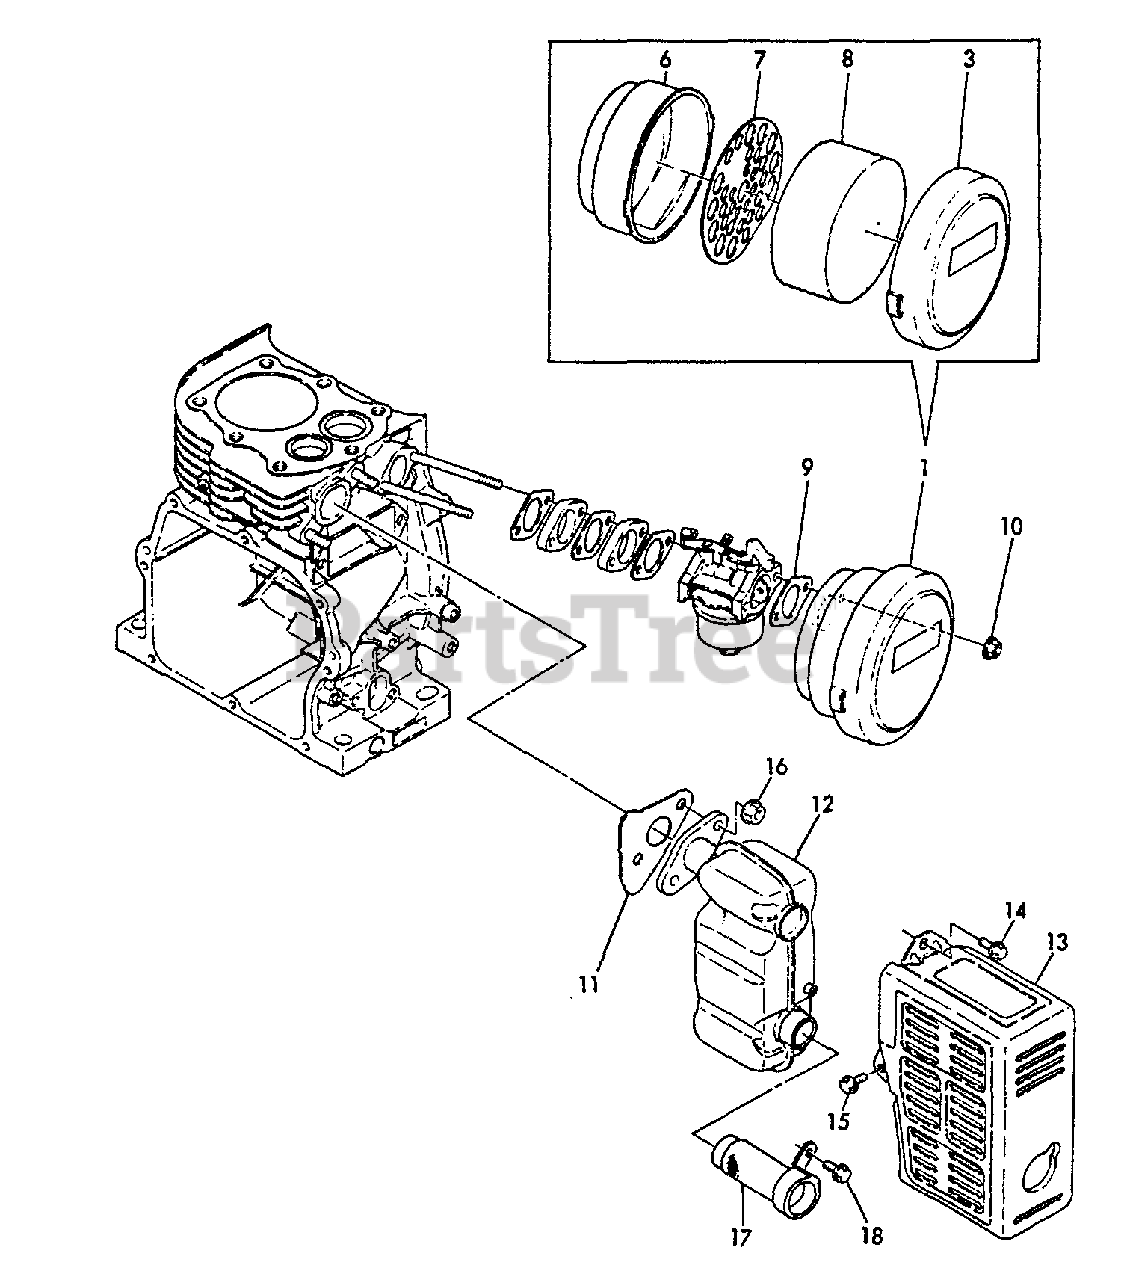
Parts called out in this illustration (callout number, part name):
1	AIR CLEANER ASSY
3	COVER, AIR FILTER
6	CASE, AIR FILTER
7	PLATE, ELEMENT
8	FILTER, AIR
9	GASKET, INTAKE
10	NUT - 6 -- FLANGE
11	GASKET, EXHAUST
12	MUFFLER
13	COVER, MUFFLER
14	BOLT - 6X12 -- PLATED
15	BOLT - 6X8 -- PLATED
16	NUT - 8
17	SCREEN, SPARK ARRESTOR
18	BOLT - 6X10 -- PLATED
